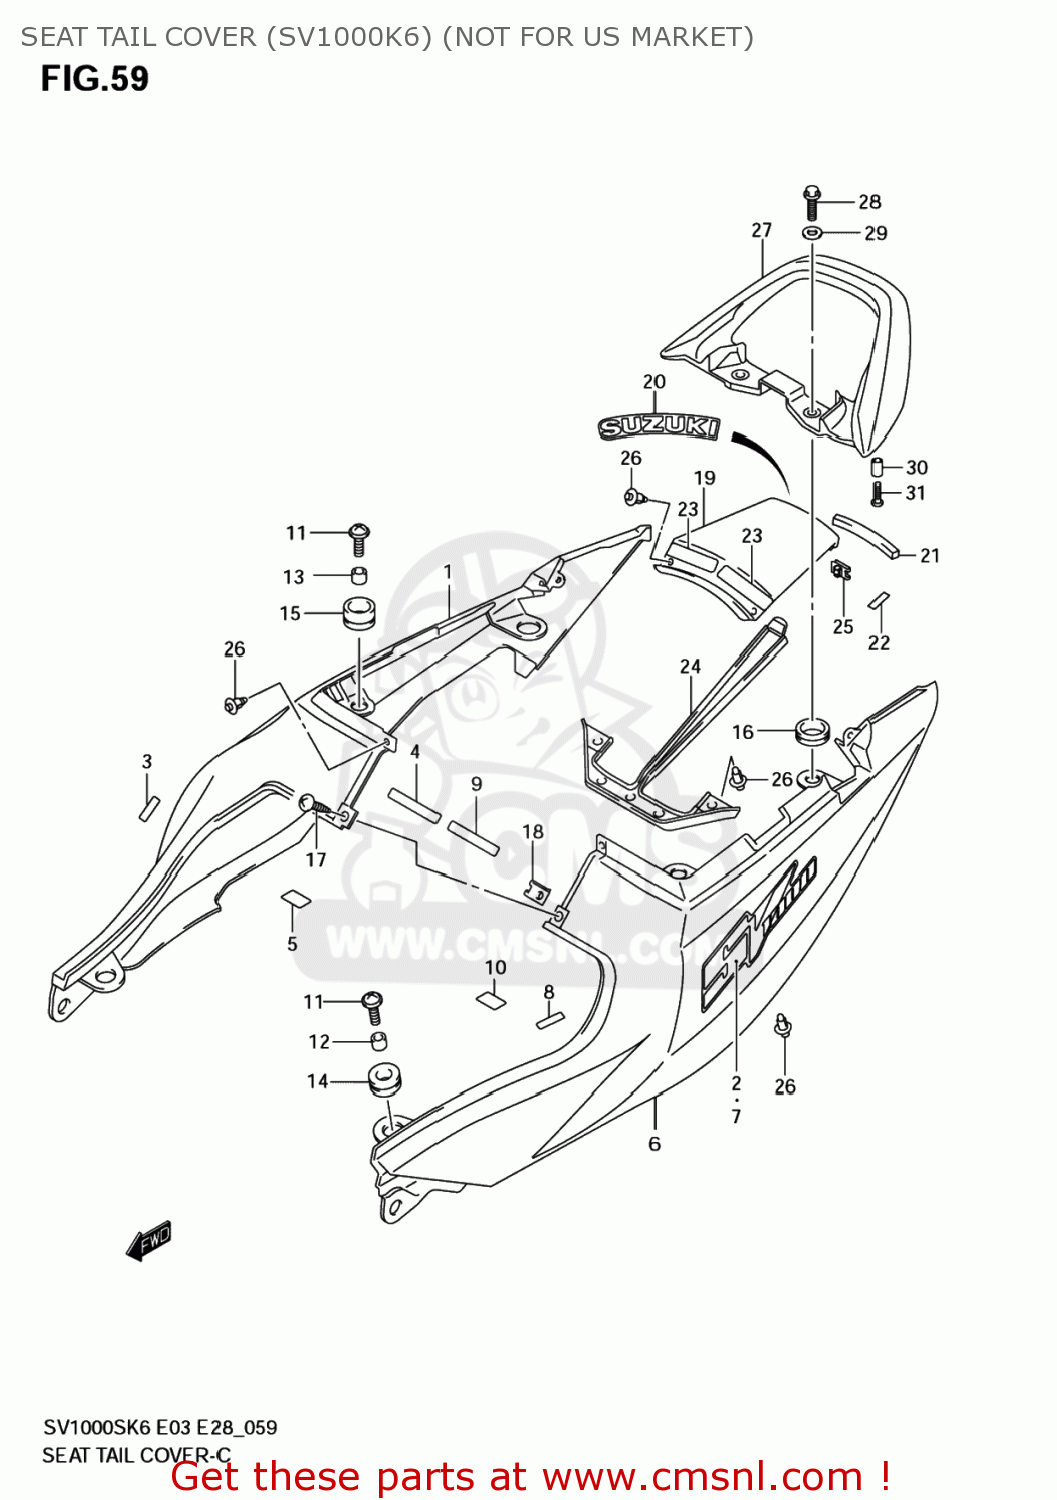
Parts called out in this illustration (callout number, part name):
1	COVER,SEAT TAIL,R(BLUE)
2	EMBLEM,SEAT TAIL COVER
3	TAPE,COVER
4	TAPE,SEAT TAIL COVER NO.2 FR
5	PROTECTOR,FRAME COVER
6	COVER,SEAT TAIL,L(BLUE)
7	EMBLEM,SEAT TAIL COVER
8	TAPE,COVER
9	TAPE,SEAT TAIL COVER NO.2 FR
10	PROTECTOR,FRAME COVER
11	SCREW(6X25)
12	SPACER(6.5X10X9.4)
13	SPACER(6.5X10X9.4)
14	CUSHION
15	CUSHION,SEAT TAIL COVER CTR
16	CUSHION
17	SCREW
18	NUT
19	COVER,SEAT TAIL CTR
20	EMBLEM,SUZUKI
21	CUSHION,SEAT TAIL COVER CTR
22	TAPE,SEAT TAIL COVER
23	TAPE,COVER
24	COVER,SEAT TAIL RR
25	NUT
26	CLIP(BLACK)
27	HANDLE,PILLION RIDER
28	BOLT
29	WASHER(8.5X24X2.3)
30	SPACER(6.5X9X18)
31	SCREW(6X25)
